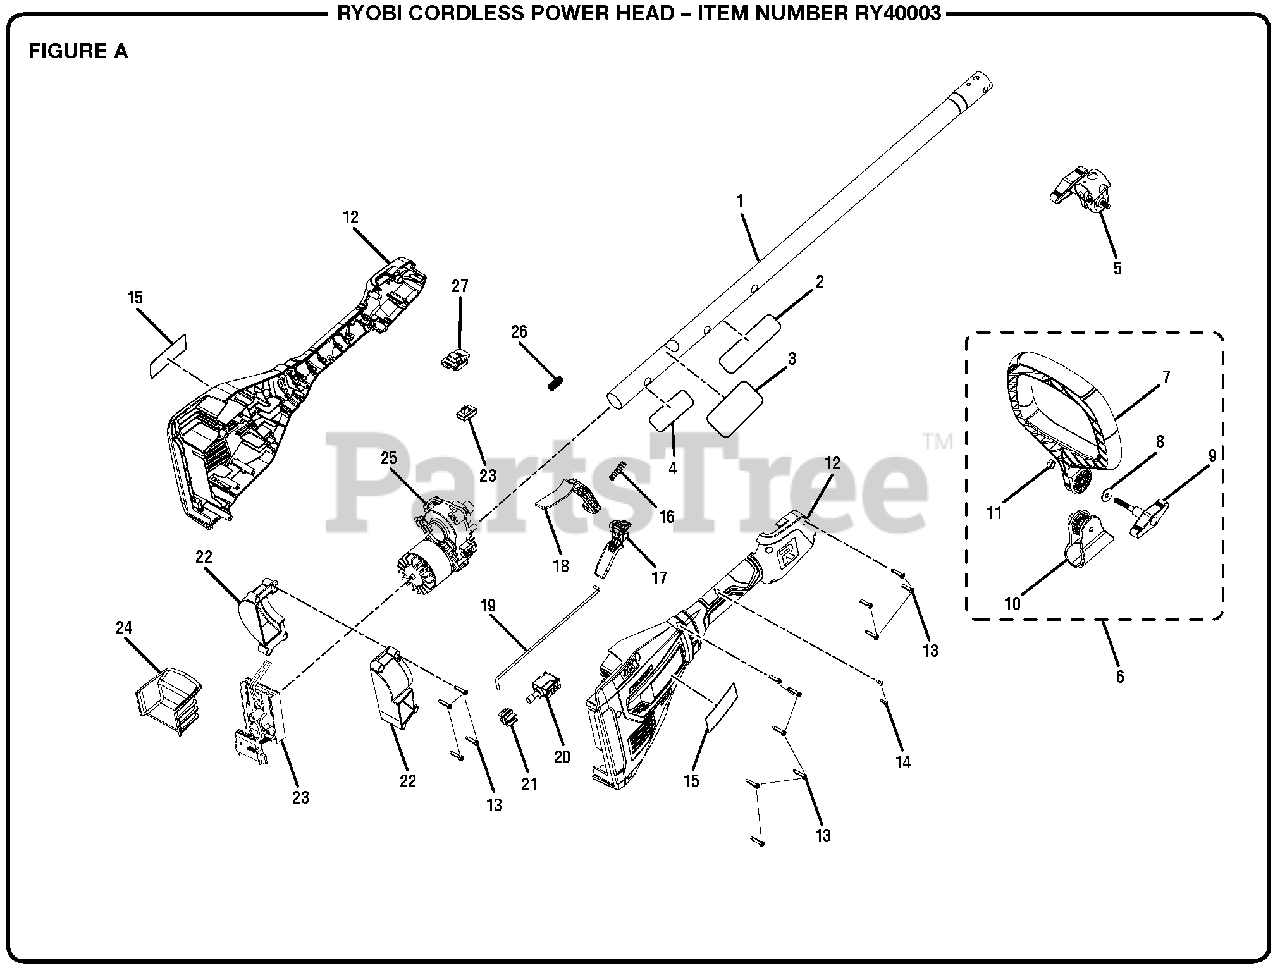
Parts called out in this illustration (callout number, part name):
1	Upper Boom Assembly
2	Warning Label (French/Spanish)
3	Warning Icon Label
4	Data Label
5	Boom Clamp Assembly
6	Front Handle Assembly
7	Front Handle
8	Washer (ID6.4 x OD18 x 1.6t)
9	Knob Assembly
10	Auxiliary Handle Bracket
11	Hex Nut (M6)
12	Rear Handle Assembly
13	Screw (M4 x 18 mm, T15 Torx Pan Hd.)
14	Screw (M3 x 8 mm, Pan. Hd.)
15	Logo Label
16	Compression Spring (Trigger Lock)
17	Switch Trigger
18	Trigger Lock-Out Lever
20	Variable Speed Switch
21	Switch Cap
22	Motor Cover
23	Electric Controller and Switch Assembly
24	Bucket Housing
25	Motor and Gear Box Assembly
26	Compression Spring
27	Slide Switch Cover
